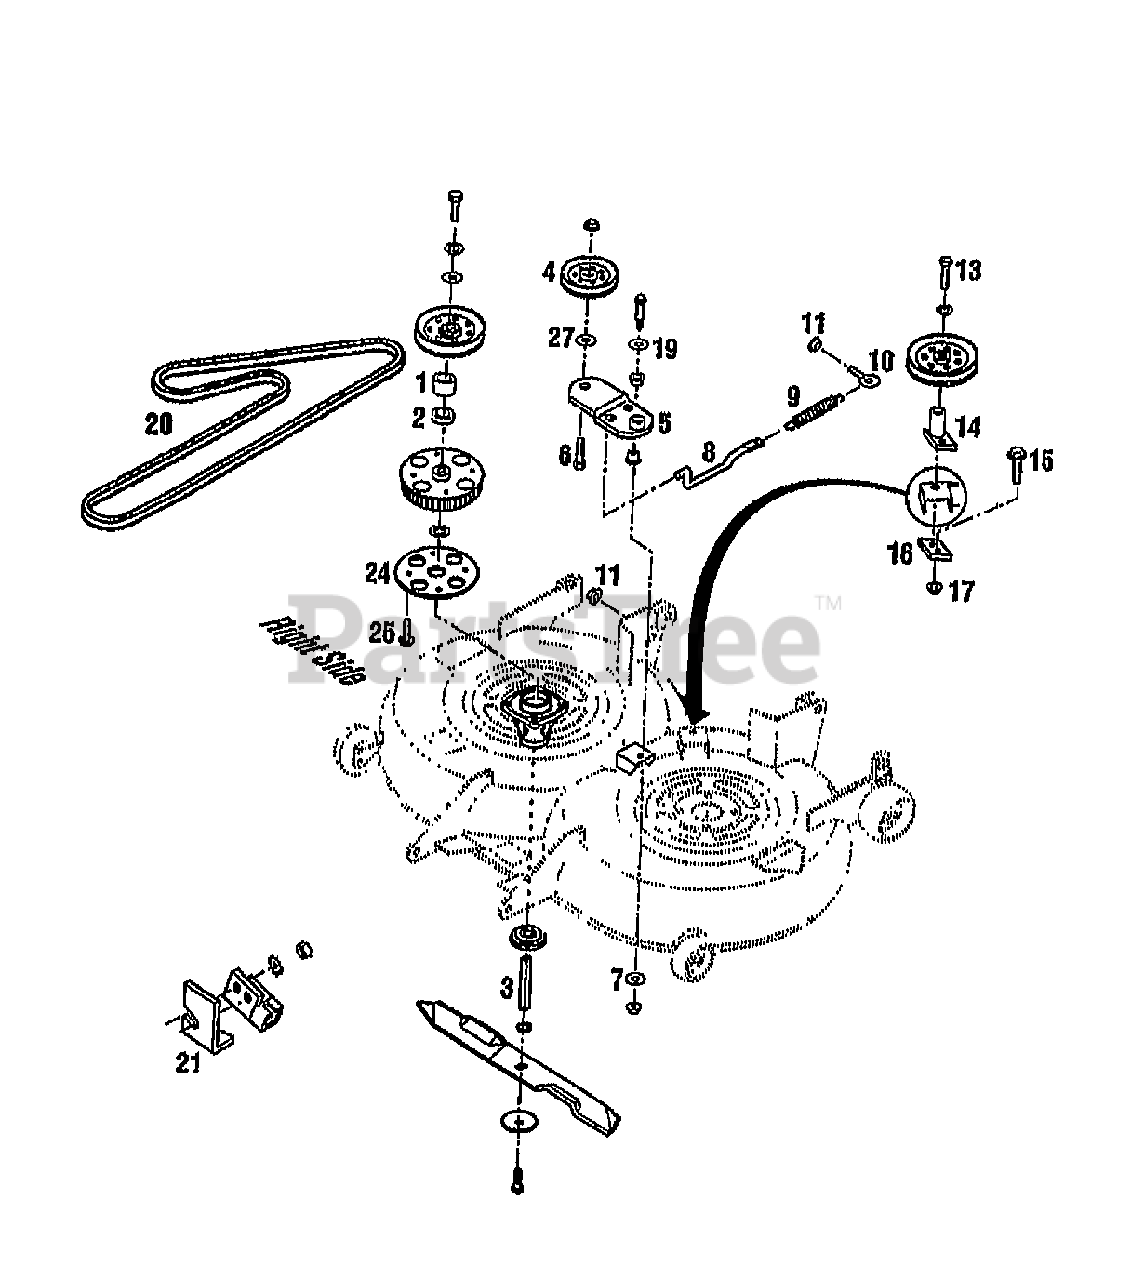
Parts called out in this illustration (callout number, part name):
1	SPACER-1.25X.77X.88
2	SPACER-1.25X.76X.50
3	SHAFT-LONG SPINDLE (RH)
4	PULLEY-IDLER
5	ASSM-IDLER ARM
6	SCR-HH 3/8-16X1.75 G5 ZP
7	WASHER-1.5X.375X.18 ZP
8	ROD-IDLER
9	SPRING
10	BOLT-EYE SC
11	NUT-HFLK 5/16-18 ZP
13	SCR-HH 3/8-16X4.00
14	PLATE-SUPPORT BLACK
15	SCR-HFLK 3/8-16X1.00 ZP
16	PLATE-SUPPORT
17	NUT-HFLK 3/8-16 ZP
21	BRACKET-SWITCH
24	PLATE-SPROCKET
25	SCR 1/4-20.75 TRI-PLASK
27	WASHER-.986X.437X.083 ZP
